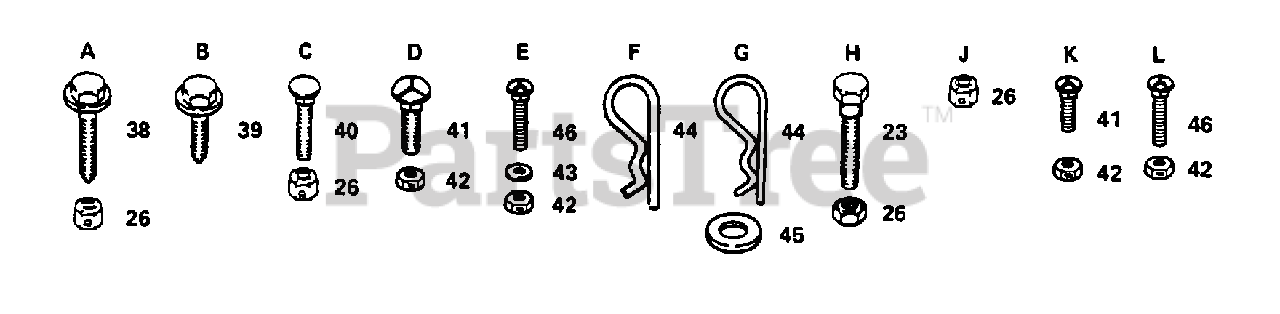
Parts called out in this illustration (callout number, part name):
23	BOLT SHOULDER LTV
38	SCREW
39	SCREW
40	BOLT
41	BOLT
43	WASHER M
46	BOLT
